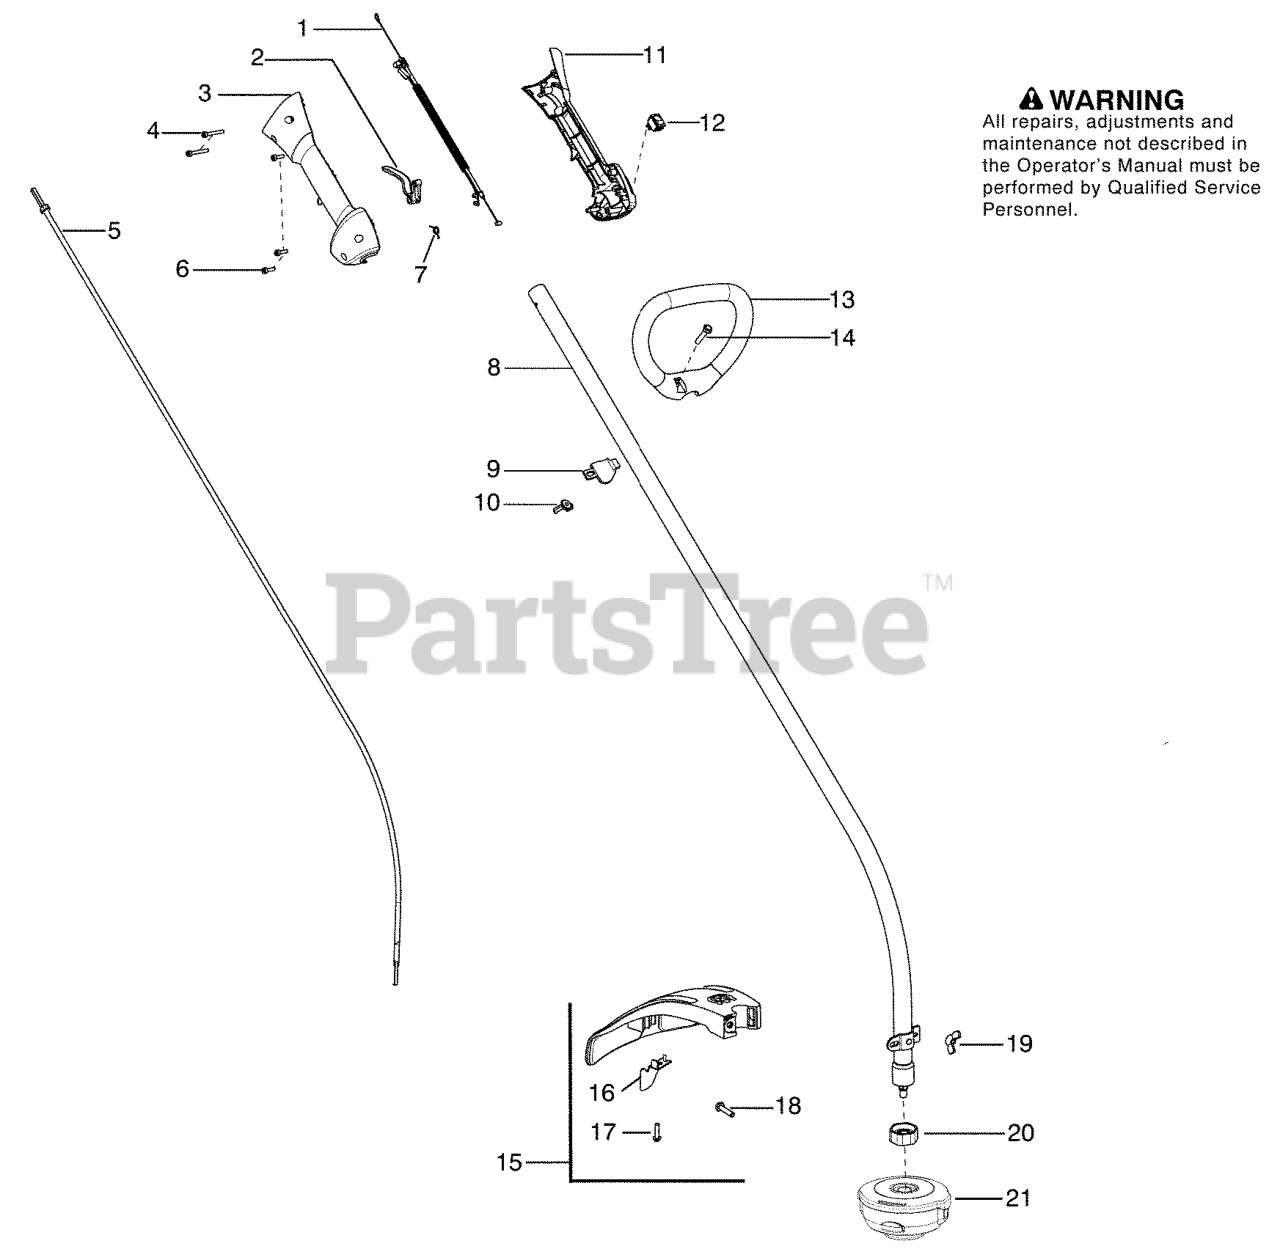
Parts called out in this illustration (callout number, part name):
1	ASSY-CABLE WIRE HARNESS
2	TRIGGER THROTTLE
3	HOUSING-THROTTLE (RH)
5	FLEX SHAFT 52"
6	SCREW M4 X 1.75 PT 16MM
7	SPRING TRIGGER
8	KIT-D'SHAFT 52" SILVER
9	CLAMP ASSIST HANDLE
10	WINGNUT, TYPE 2
11	HSG THROTTLE LH
12	KIT SWITCH
14	BOLT, TYPE 2
15	TRIMMER GUARD 128C
16	KIT - LIMITER - LINE
18	BOLT, TYPE 2
19	WINGNUT, TYPE 2
21	T25 TRIM HEAD RH
